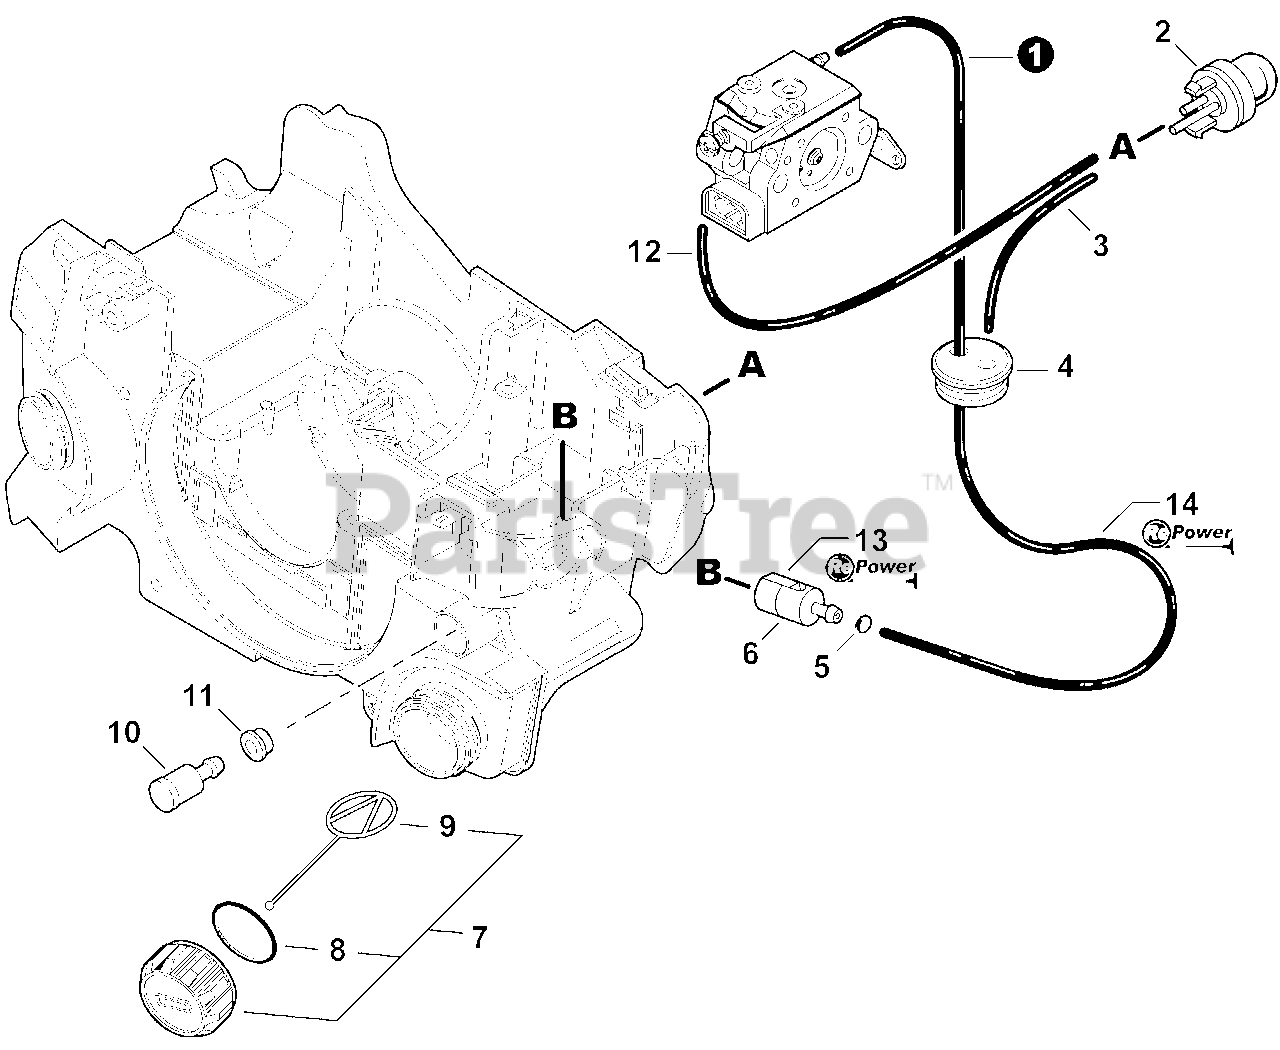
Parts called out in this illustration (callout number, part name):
1	PIPE, FUEL 3×5×230 BLACK
2	BULB, PURGE
3	PIPE, FUEL 2.4×5×80 BLACK
4	GROMMET, FUEL
5	CLIP 6 MM
6	FILTER, FUEL
7	CAP ASSY, FUEL
8	O-RING 22
9	CONNECTOR, CAP L= 60 MM
10	VENT ASSY
11	GROMMET, FUEL
12	PIPE 2.4×5×125 BLACK
13	TUNE-UP KIT - REPOWER
14	BULK PIPE - 3×5 MM BLACK (4 PIECES×2 M)
